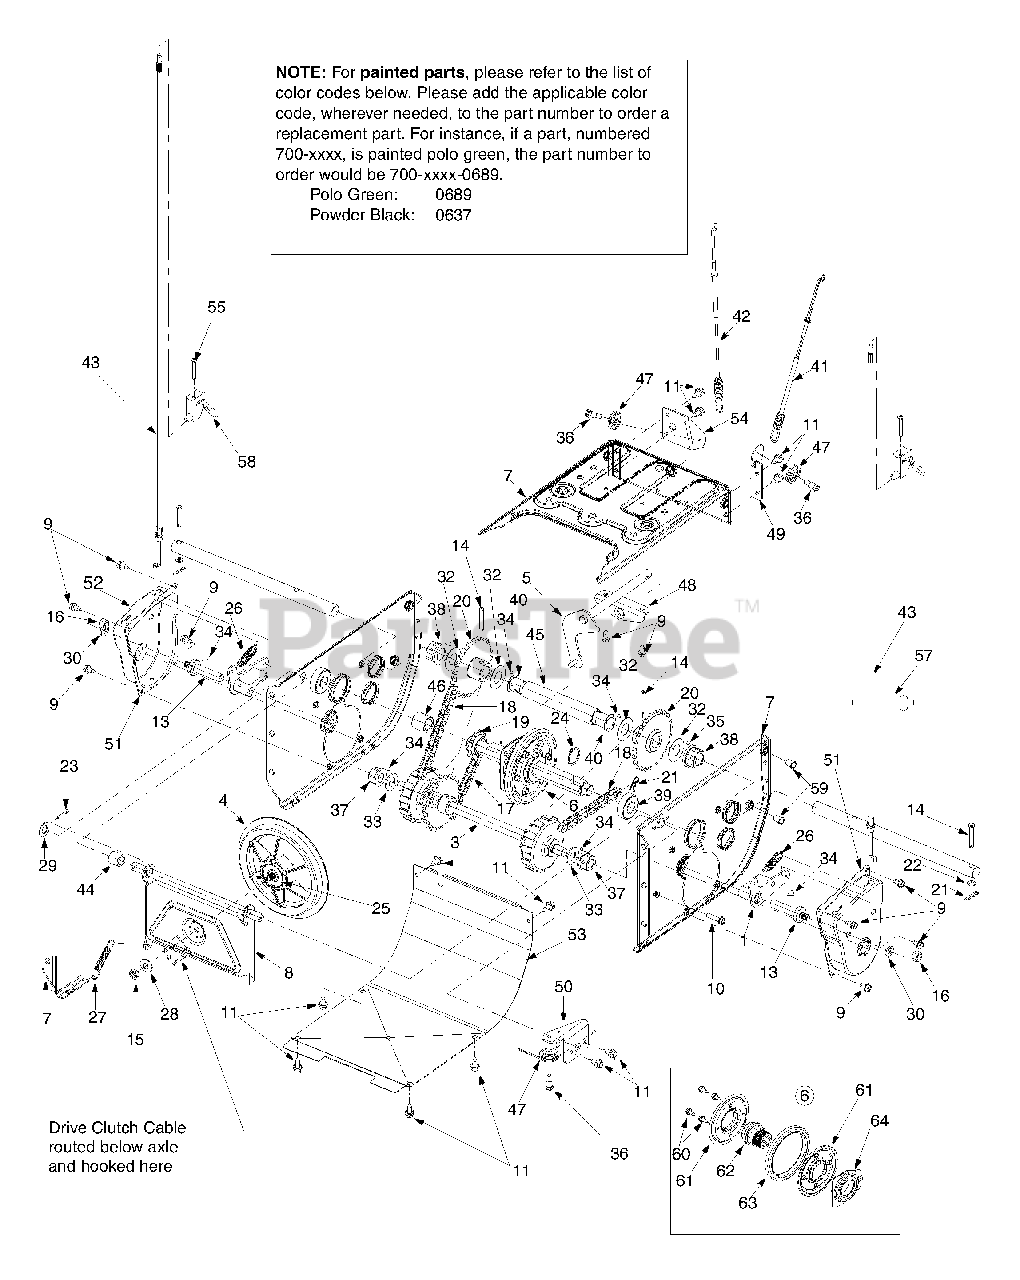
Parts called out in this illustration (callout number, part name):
1	Dogg Assembly RH
3	Shift Assembly: Steerable Drive
4	Friction Wheel Disc Assy.
6	Friction Wheel Assembly
7	Transmission Frame
10	TT Screw 1/4-20 x 1.25"
11	TT Screw 1/4-20 x .625"
13	Actuator Shaft
15	Jam Nut 3/8-24 Gr.8
16	Hex Nut: 3/8-16
17	Chain
18	Chain
19	Sprocket: 10T
20	Sprocket
21	Cotter Pin
22	Flat Washer
23	Cotter Pin
24	Snap Ring
25	Adhesive: Loctite (TM)
26	Extension Spring
27	Extension Spring
28	Bell Washer
29	Flat Washer
30	Lock Washer
32	Flat Washer
33	Flat Washer
35	Grease
36	Shoulder Screw
37	Hex Flange Bearing
38	Hex Flange Bearing
39	Ball Bearing
40	Flange Bushing
41	Auger Clutch Cable
42	Drive Clutch Cable
43	Steering Cable
44	Spacer
45	Support Tube: Axle
46	Spacer
47	Roller Cable
57	Cable Tie
58	Turn Trigger
59	Nut Insert
60	TT Screw 1/4-20 x .625"
61	Friction Plate
62	Friction Wheel Rubber
63	Friction Wheel Hub
64	Friction Wheel Bearing
